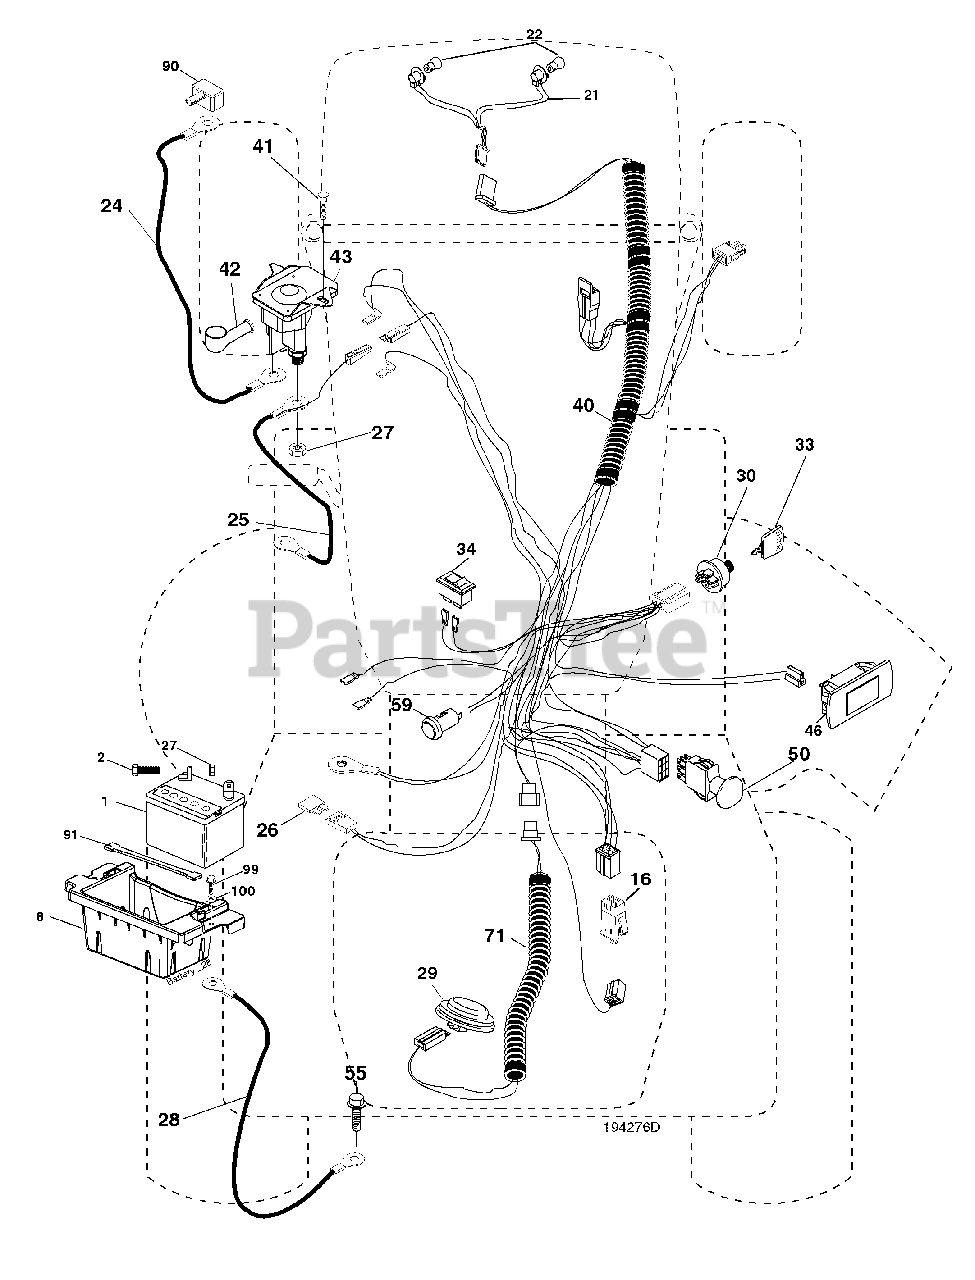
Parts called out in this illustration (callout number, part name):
1	Battery
2	Bolt Hex Hd 1/4-20 unc x 3/4
8	Battery Box
16	Switch Interlock
21	Harness Socket Light
22	Bulb, Light # 1156
24	Cable Battery
25	Cable Starter
27	Nut Keps Hex 1/4-20 unc
28	Cable Ground 21" Blk 6 Ga.
29	Switch Seat
30	Switch Ign
33	Key Ign Molded Generic
34	Switch Light/Reset
40	Harness Ign
41	Bolt Fin Hex 1/4-20 unc x 1/2
42	Cover Terminal Red
43	Solenoid
46	Gauge Hourmeter
50	Switch PTO
55	Screw Thdrol 5/16-18 x 1/2
59	Outlet 12-Volt
71	Harness Ign. Dash
90	Cover Terminal Battery
91	Strap Battery
99	Screw Hexwsh Thdrol 1/4-20 x 3/4
100	Washer 9/32 x 7/8 x 16 Ga.
